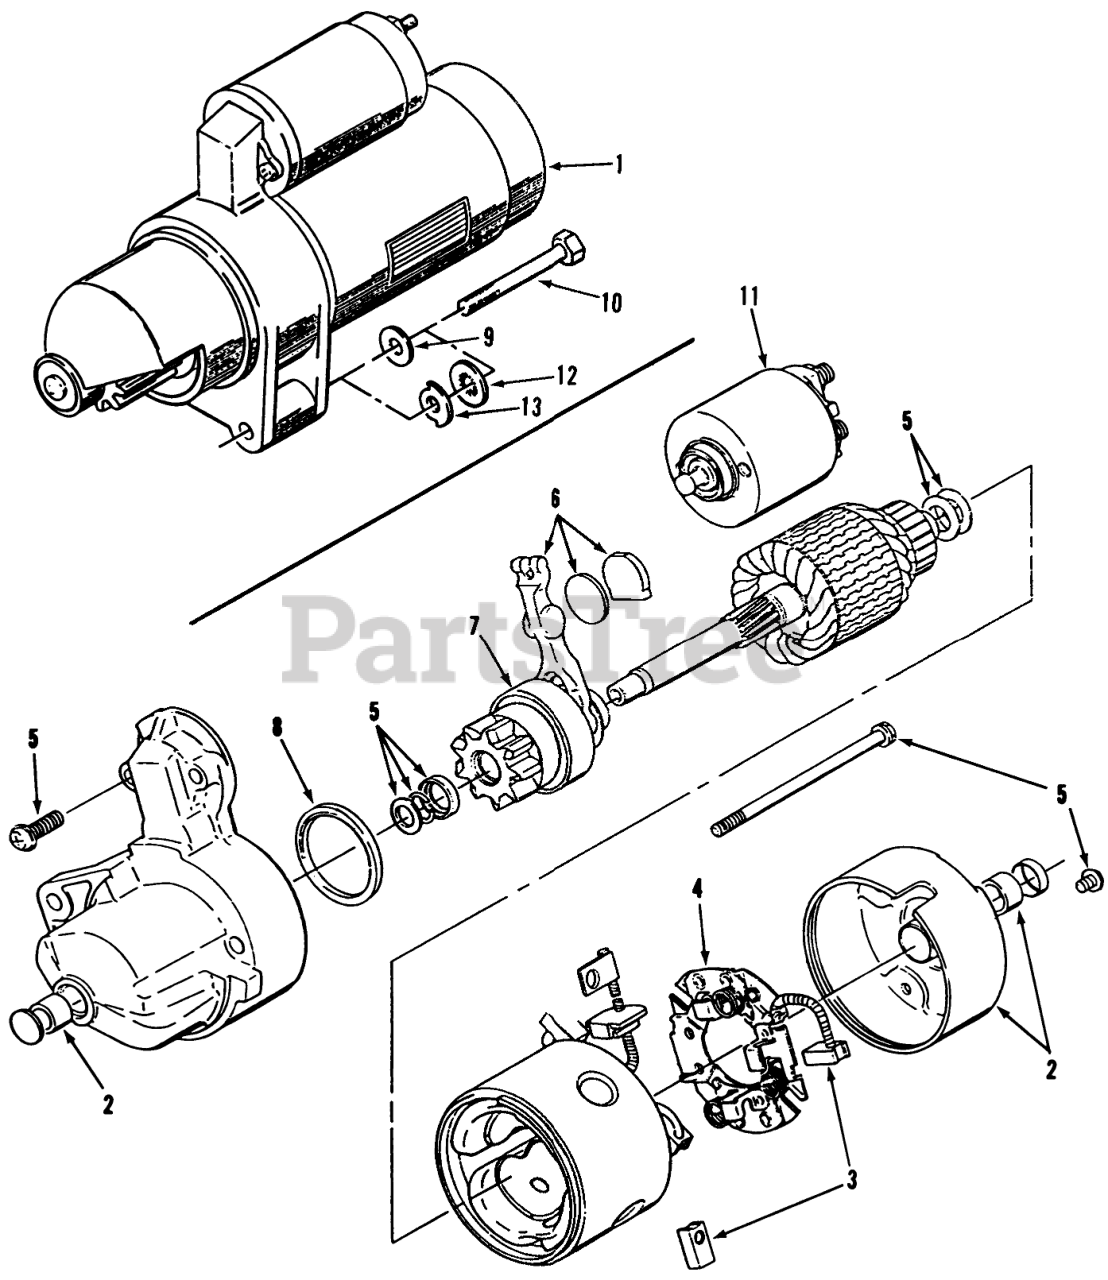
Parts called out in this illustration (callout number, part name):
1	Starter, Complete-See Components Below
2	Bushing Kit (Includes Frt Bushing and Rear Cap w/Bushing)
3	Starter Brush Kit (Includes Positive Brush 2] and Negative Brush w/Pigtail)
4	Starter Brush Holder (Includes Brush Holder w/Negative Brush)
5	Starter Hdwr Kit (Includes Solenoid Screws 2], Brush Holder Screws 2], Thru Bolts 2], Armature Shims 2], Pinion Stop Collar, and Pinion Retaining Ring)
6	Starter Shift Lever Kit (Includes Shift Lever, Wear Plate and Rubber Plug)
7	Starter Clutch (Includes Pinion Gear w/Clutch)
8	Dust Seal
9	WASHER
10	Bolt
11	Starter Solenoid Kit (Includes Solenoid, Spring and Plunger)
12	WASHER
13	WASHER
